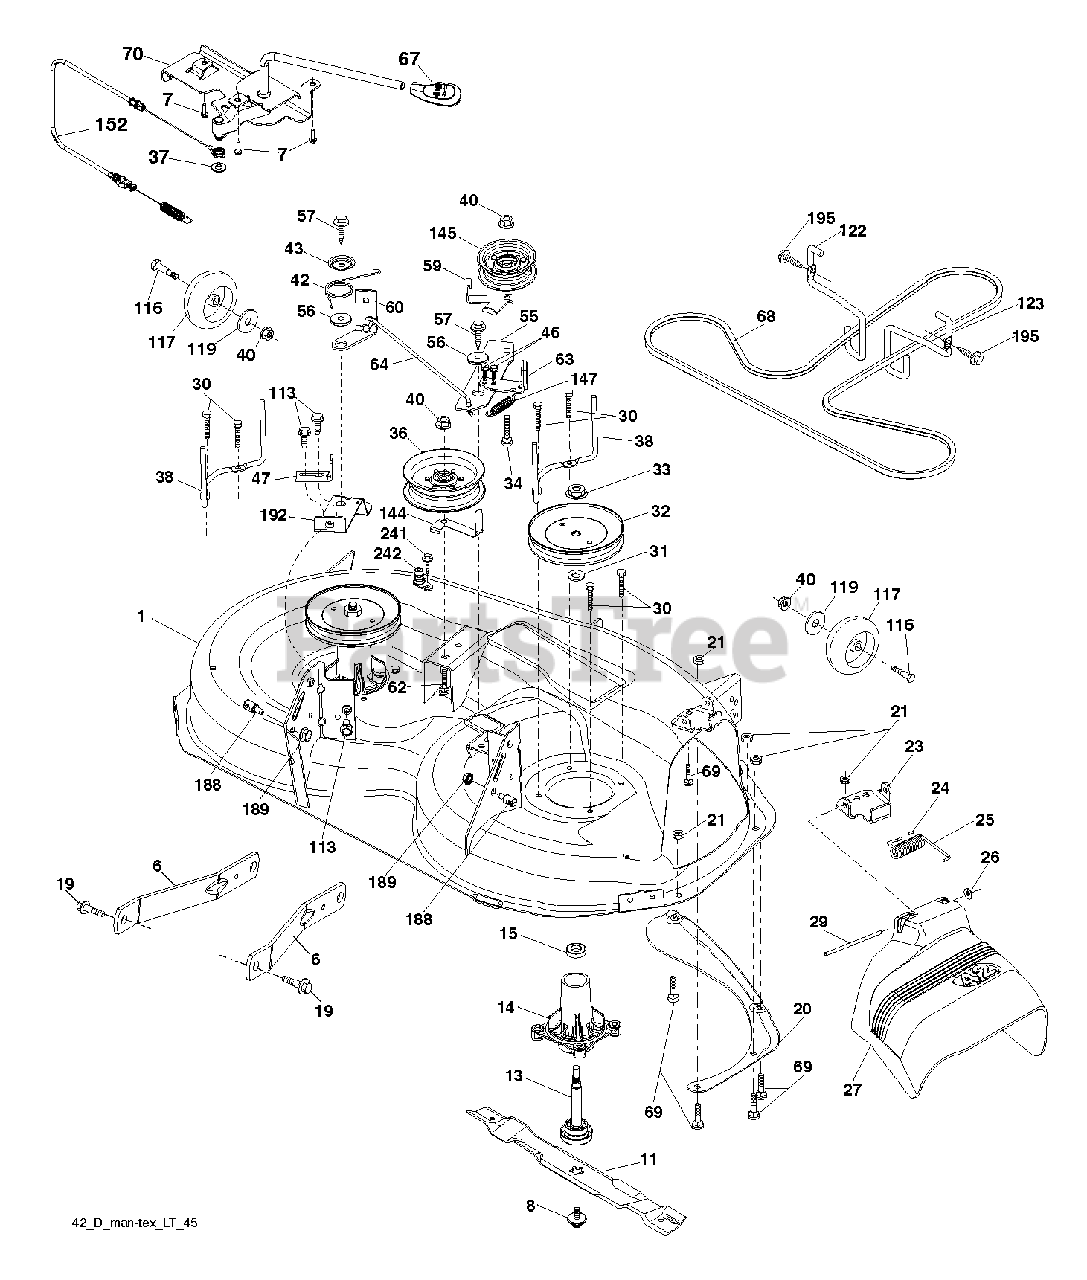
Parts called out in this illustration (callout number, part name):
6	ARM.SUSPENSION.MOWER.R
7	SCREW.#10 X 0.750.BOS (2 2)
8	BOLT.WASHER.ASM.7/16-2
11	42" HI-LIFT BLADE
13	SHAFT.ASM.MDRL.N/GREASE.38
14	HOUSING.MANDREL.4PT.
19	BOLT.SHOULDER
20	BAFFLE.VORTEX
21	LOCKNUT
23	BRKT.DEFLECTOR.38"2005+
24	CAP-SLEEVE LT
25	SPRING.TORSION.DEFLECT
26	NUT PUSH M
27	SHIELD.DEFLECTOR.MOWER.42"BLAC
29	ROD.HINGE
30	SCREW, WASHER HEAD
31	WASHER.SPACER.MANDREL
32	PULLEY.MANDREL.5.438.PD
33	NUT.FLANGE.LOCK.TOP
34	BOLT.3/8-16X1.50
36	PULLEY.IDLER.2006
38	KEEPER.BELT.MANDREL.PULLEY
40	NUT LOCK FLG 3/8-16 UNC
42	SPRING.TORSION.BRAKE
43	SRPING.TORSION.RETAINE
46	SCREW.1/4-20X5/8
47	BRKT.CLUTCH.CABLE
55	IDLER.ARM
56	SPACER.RETAINER
57	SCREW 3/8-16X1
59	GUARD, BELT
60	ARM BRAKE MOWER
62	BOLT
64	LINK BRAKE
67	HANDLE.CLUTCH.CABLE.LT
68	BELT.DECK.DRIVE.42"
69	BOLT
70	CLUTCH.ASM.MANUAL.LT.TEX
113	BOLT.5/16HEX.WHS.HD
116	BOLT M
117	WHEEL.GAGE.HALF.SPOKED
119	WASHER
122	KEEPER BELT ENGINE LH
123	KEEPER BELT RH
144	KEEPER.BELT.MOWER
145	PULLEY.IDLER.48"PRIMARY
147	RETURN SPRING
152	CABLE.CLUTCH.MANUAL.
188	STUD.FASTNER.W/ANTI-ROTATE
189	NUT LOCK HEX FLANGE 5/16-18
192	BRKT.BRAKE.STAND.LH.
195	SCREW, 3/8-16X3/4
241	SCREW.TT.#10-32X.5.3/8.FLANGE
242	PORT.WASHOUT
